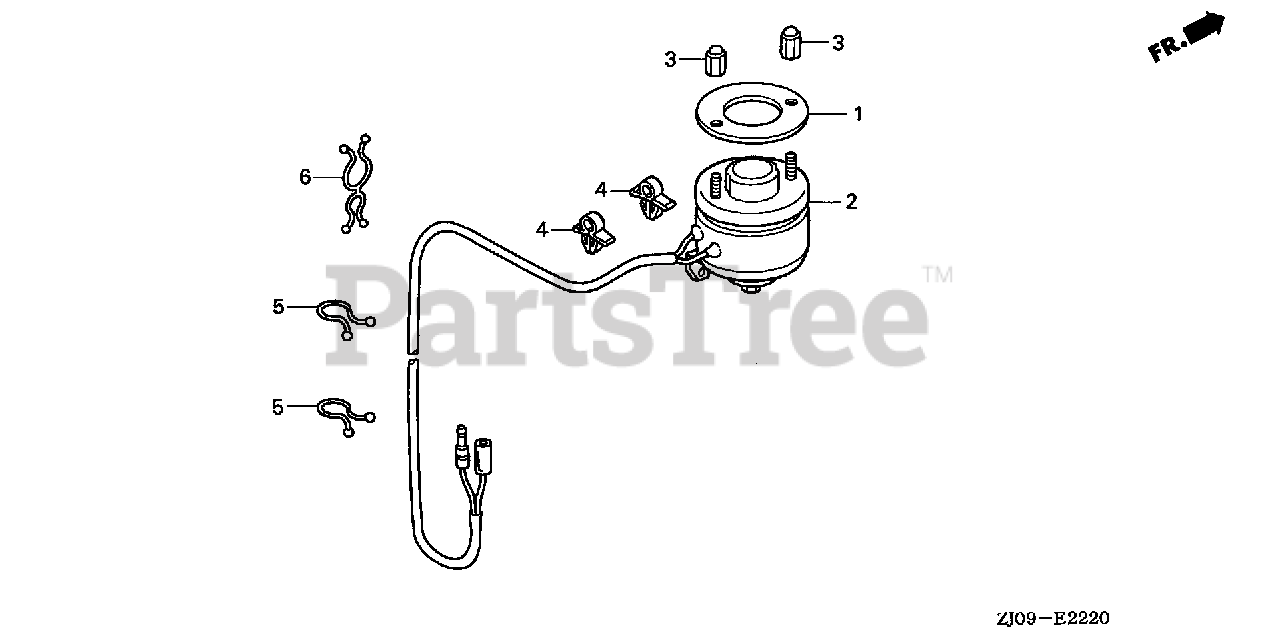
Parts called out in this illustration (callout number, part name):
1	PLATE, SOLENOID
2	SOLENOID ASSY., ROTARY
3	NUT, SPECIAL CAP
4	CLIP, WIRE HARNESS (6MM) (WHITE)
5	CLIP, PURSE LOCK (8MM)
6	CLIP, PURSE LOCK
